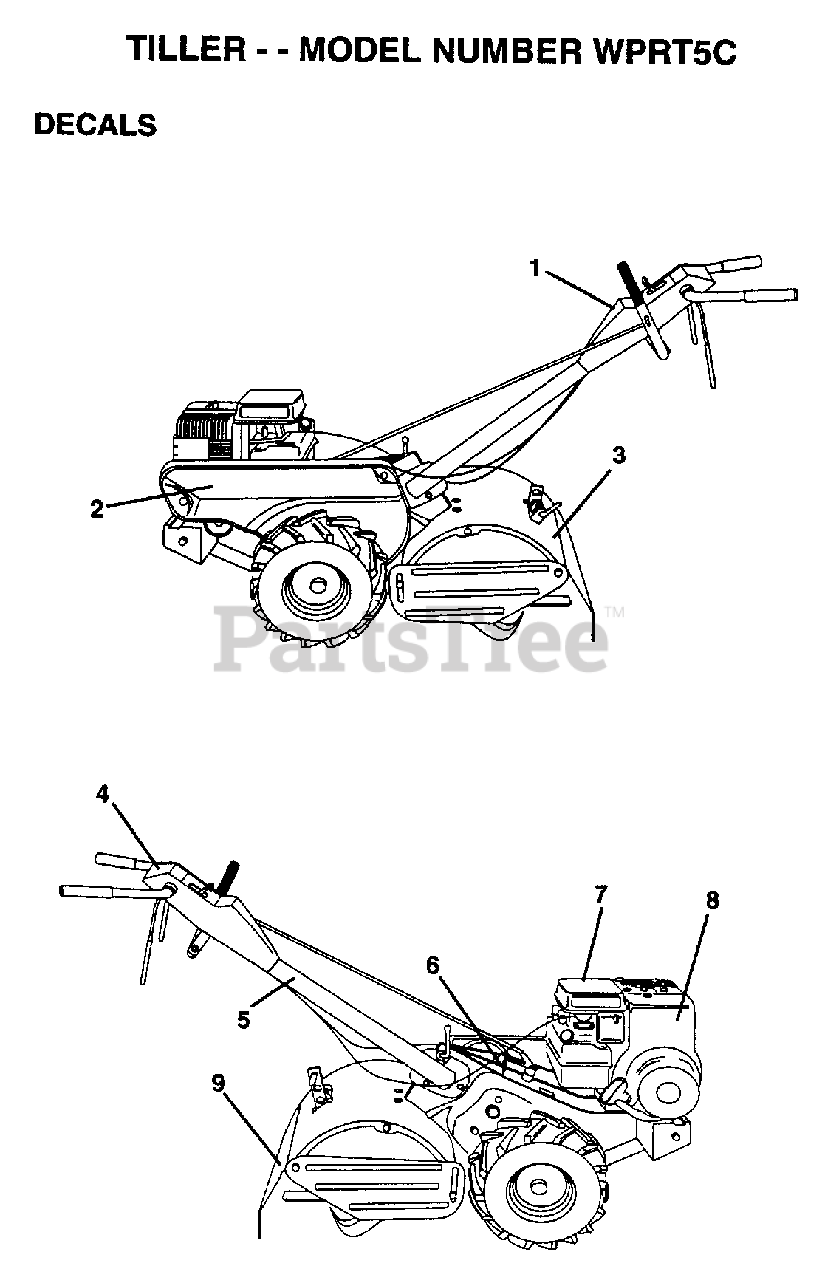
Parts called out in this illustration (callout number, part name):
1	DECAL.PNL.CONTROL
2	DECAL.GD.BELT.5HP
3	DECAL.SHLD.TINE
4	DECAL.INSTRUCTION
5	DECAL TI
6	DECAL CRT
8	DECAL, BRIGGS & STRATTON
9	DECAL TI
